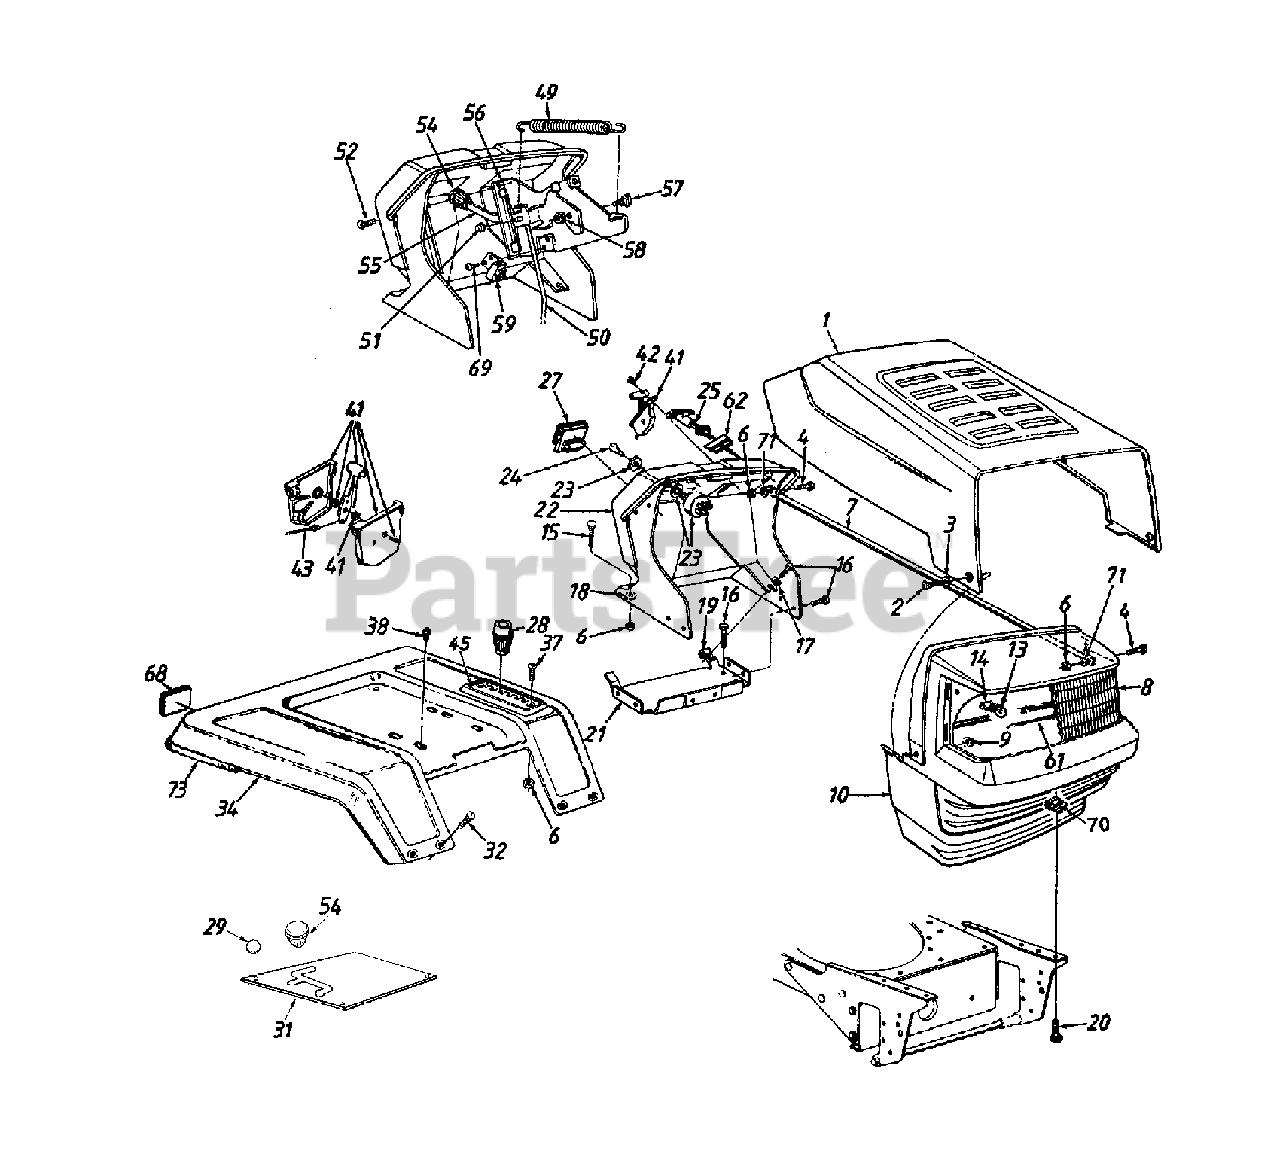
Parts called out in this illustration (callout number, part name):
3	Spr. Washer .265" I.D. x .562" OD
4	Hex Bolt 1/4-20 x .62"
6	Hex Sems Nut 1/4-20 Thd.
9	Flange L-Nut 1/4-20 Thd.
10	Grille
13	Lamp
14	Socket
15	Carriage Bolt 1/4-20 x 1.0"
16	Hex AB-Tap Scr. 1/4 x .62"
17	Flat Washer .281" I.D. x .73" O.D.
18	Bolt Retainer 1/4" I.D.
19	Speed Nut 1/4-20 Thd.
20	Hex Bolt 5/16-18 x .75"
23	Ignition Switch
24	Ignition Key
25	Choke Control
27	Ammeter
28	Shift Knob
38	Hex Washer Hd. AB-Tap Scr. 5/16 x .75"
41	Throttle Box Assembly
42	Truss Mach. AB-Tap Scr. #10 x .5"
43	Throttle Control Wire 35"
45	6-Speed Selector Plate (820)
49	Ext. Spring 5.06"
50	Deck Control Rod
51	Speed Nut 1/4" Rod
52	Torx Mach. Scr. 1/4 x .62"
54	PTO Knob
55	PTO Lever
58	Hex L-Nut 5/16-18 Thd.
59	Safety Switch
61	Grille Reflector Label
62	Retainer Clip
68	Reflector
69	Hex Washer Hd. B-Tap Scr. #10 x .38"
70	U-Nut 5/16-18 Thd.
71	Flat Washer .28" I.D. x .75" O.D.
73	Trim Strip 81"
17426A-0638	FENDER-RR - MTD/TROY-BILT RED (0638)
17426A-0648	FENDER-RR - TECH GRAY (0648)
